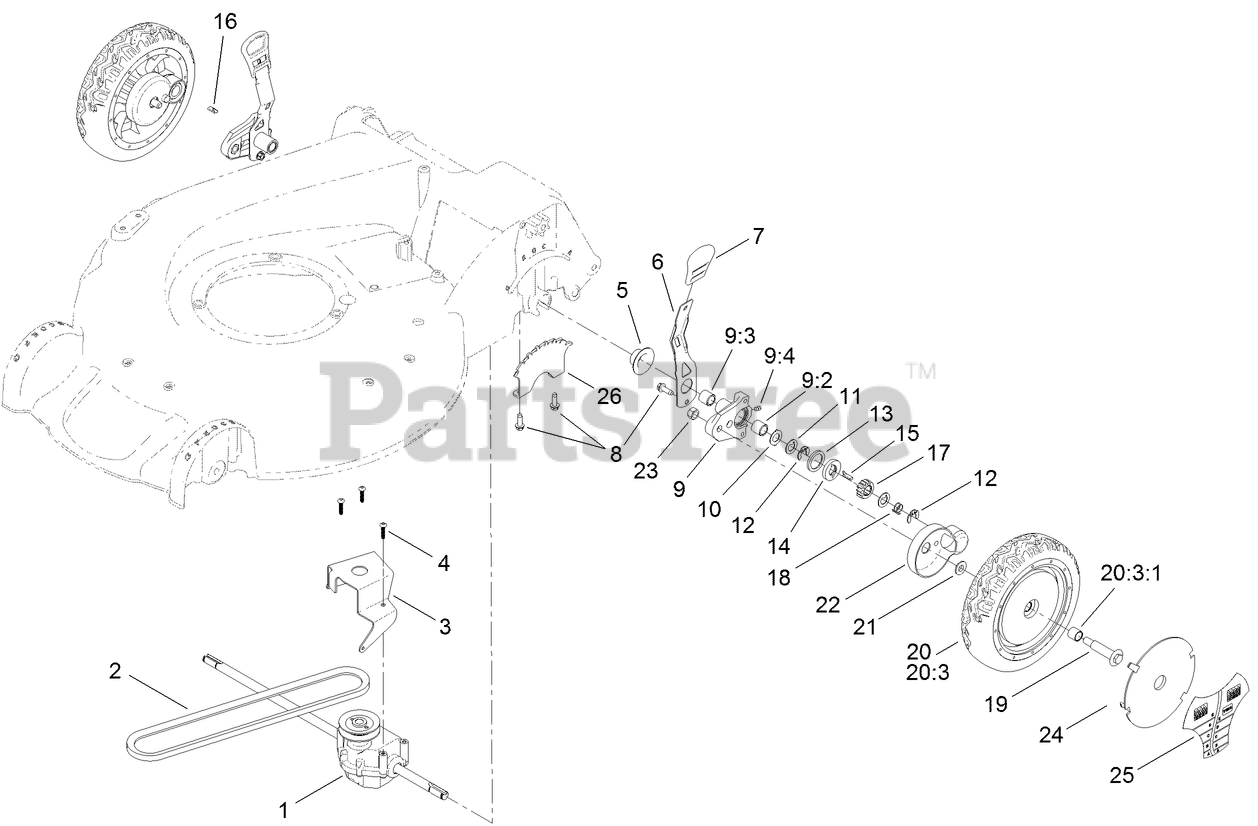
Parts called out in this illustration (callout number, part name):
2	V-BELT
3	BRACKET-TRANSMISSION
4	SCREW-PLASTITE
5	CAP-END
6	ARM-SPRING
7	KNOB-HOC
8	SCREW-HWHTF
9	PIVOT ARM ASM
9:2	BUSHING
9:3	BUSHING
9:4	FITTING-GREASE
10	WASHER-ARM, PIVOT
11	WASHER-THRUST, KEYED
12	RING-RETAINING,CLIP
13	RING-FRICTION
14	WASHER-CLUTCH
15	KEY-ROCKING, LH
16	KEY-ROCKING, RH
17	GEAR-PINION
18	SPRING-COMPRESSION
19	BOLT-SHOULDER
20	8 INCH WHEEL AND GEAR ASM
20:3	Loose Parts Package
20:3:1	BUSHING
21	SPACER-COVER, WHEEL
22	COVER-WHEEL
23	LOCKNUT
24	COVER-WHEEL
25	LABEL-WHEEL, SMART
26	PLATE-HOC
